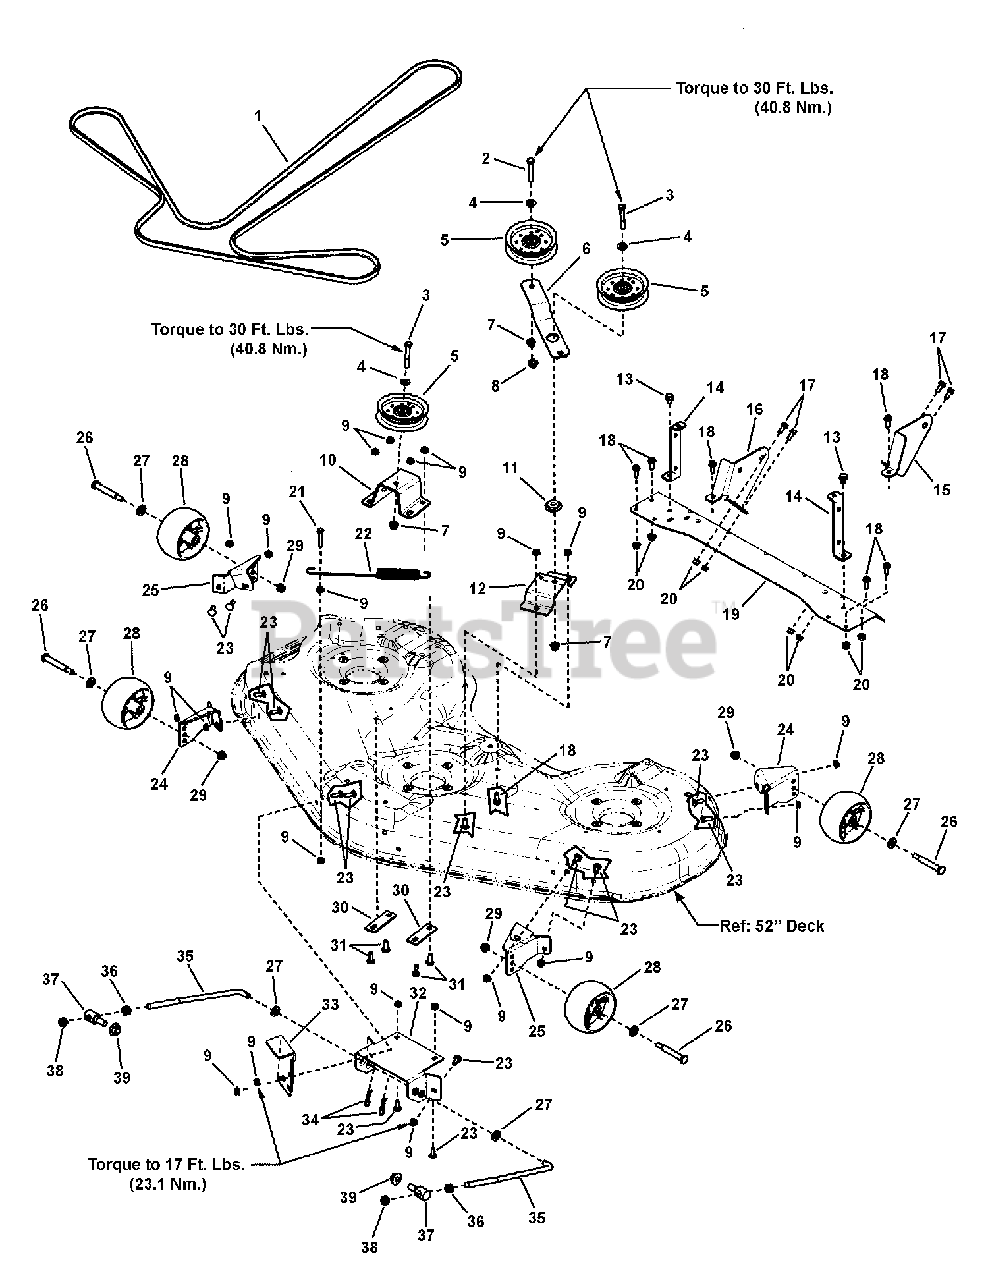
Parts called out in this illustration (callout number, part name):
1	* V-BELT, (HA Sect., 132" Effective Length)
2	SCREW, 3/8-16 x 2-1/2" Hex Head Cap, GR 5
3	SCREW, 3/8-16 x 2-1/2" Hex Head Cap, GR 5
4	WASHER, .375 Flat (.41 I.D. x .87 O.D.)
5	PULLEY, Idler
6	ARM, Idler
7	NUT, 3/8-16 Hex Flange Lock
8	NUT, 3/8-16 Hex Large Flange
9	NUT, 5/16-18 Hex Flange Lock, Small - Black
10	BRACKET, Fixed Idler, Rear
11	SPACER, .406 I.D. x 1.50 O.D. x .350 Thick Powdered Metal
12	BRACKET, Idler Mount, Front
13	SCREW, 3/8-16 x 1/2" Washer Head Self-Tap
14	UPSTOP, Rear, 52" Mower
15	BRACKET, Rear Mower Pickup, LH
16	BRACKET, Rear Mower Pickup, RH
17	SCREW, 5/16-18 x 3/4" Hex Flange Lock
18	SCREW, 5/16-18 x 1" Hex Washer Head Self-Tap
19	SUPPORT, Rear Cross
20	NUT, 5/16-18 Hex Flange Nyloc
21	SCREW, 5/16-18 x 1-3/4" Hex Head Cap, GR5
22	SPRING, Extension
23	BOLT, 5/16-18 x 7/8" Round Head Short Square Neck Carriage, GR5
24	BRACKET, Gauge Wheel, LH
25	BRACKET, Gauge Wheel, RH
26	BOLT, Shoulder (Gage Wheel) 3/8-16 x 3.41 x 3/4"
27	WASHER, 1/2" Flat (0.51 I.D. x 1.00 O.D. x .10 Thick)
28	WHEEL, Gage (5" Dia.) Black Polypropylene
29	NUT, 3/8-16 Hex Flange Nyloc
30	PLATE, Backing
31	BOLT, Carriage, Short Neck, 5/16-18 x 1
32	HITCH, Front, 52" Mower
33	UPSTOP, 52" Deck
34	CLIP, Hair Pin .093 Dia.
35	ROD, Front Rail, 52" Mower (1/2-13 Thread)
36	NUT, 1/2-13 Hex Jam
37	TRUNNION, 1/2-13 Thread
38	NUT, 1/2-13 Hex Jam
39	NUT, HEX FLANGE 1/2-13 Hex Flange Two Way Lock
